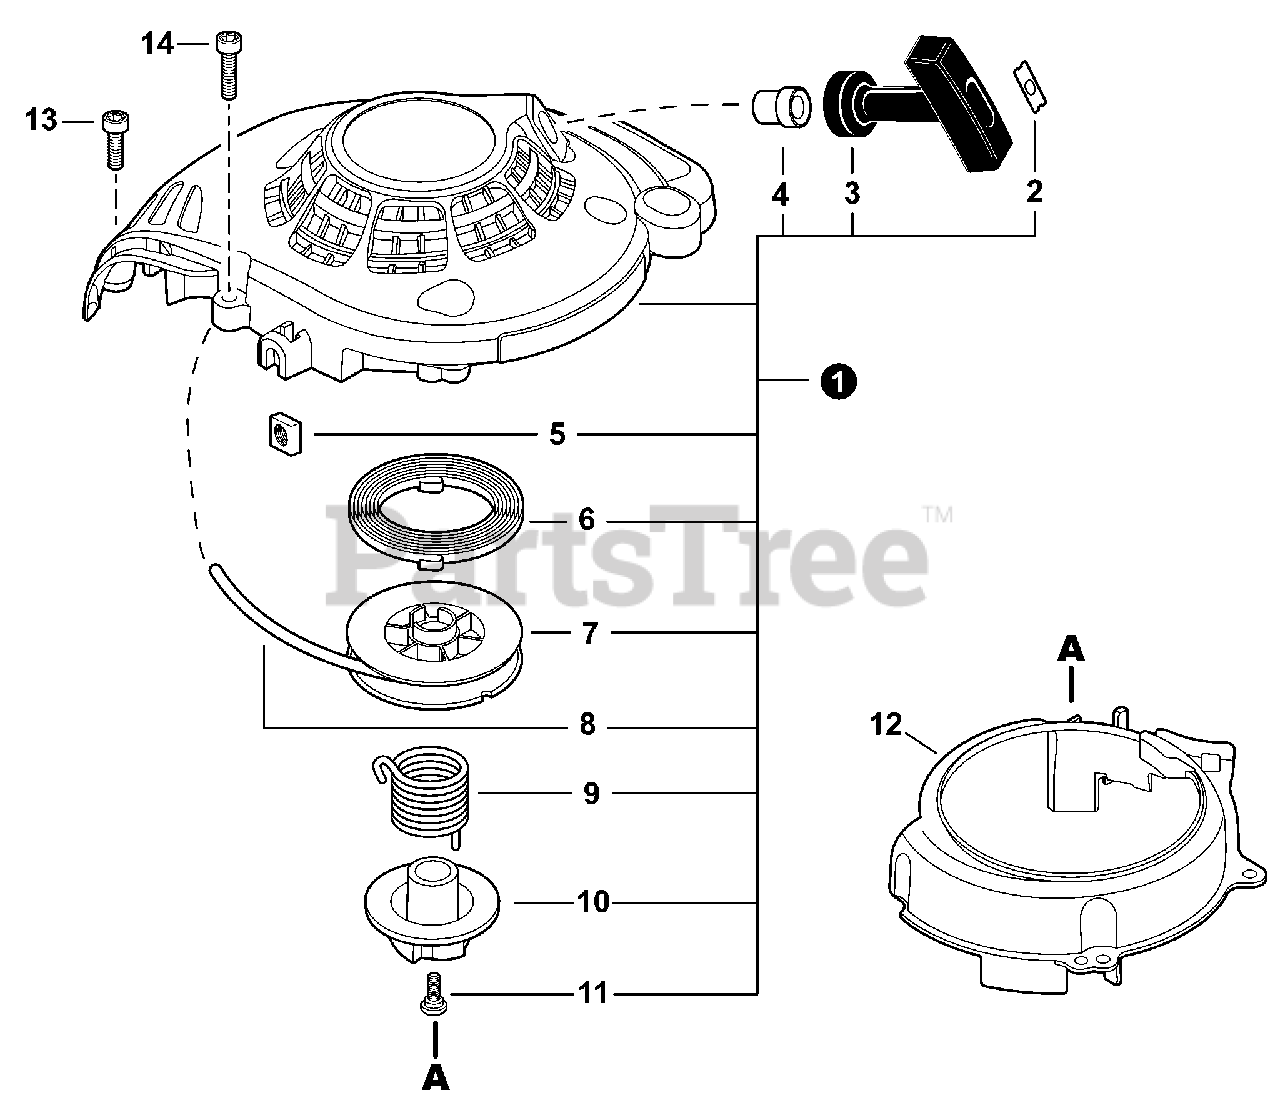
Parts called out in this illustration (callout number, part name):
1	STARTER ASSY, RECOIL
2	RETAINER, ROPE
3	GRIP, STARTER
4	GUIDE, ROPE
5	NUT M5
6	SPRING, RECOIL
7	REEL, ROPE
8	ROPE, STARTER 3×700
9	SPRING, TORSION
10	PLATE, CAM
11	SCREW
12	COVER, FAN
13	BOLT, TORX 4×16
14	BOLT, TORX 4×16
